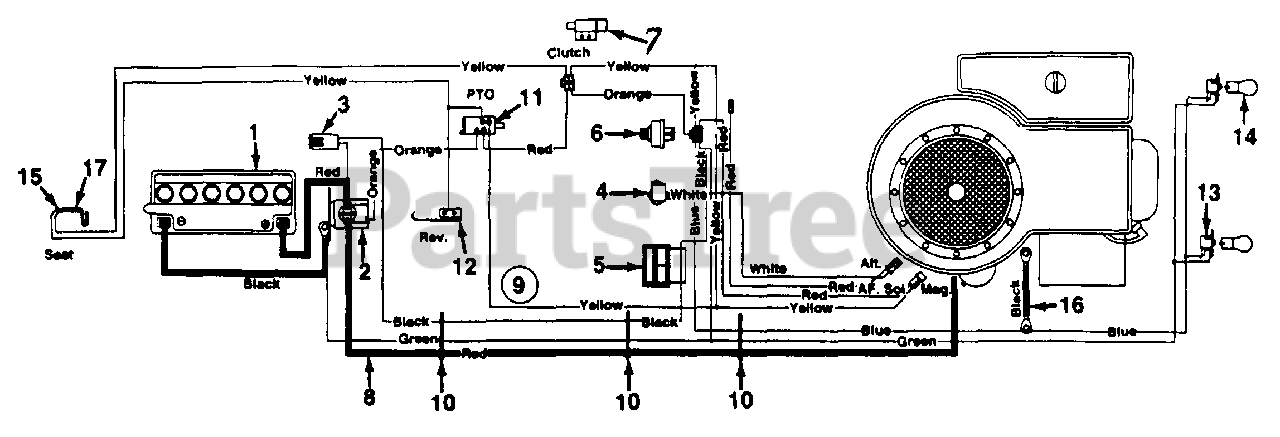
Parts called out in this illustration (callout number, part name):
1	Battery
2	Solenoid
3	Fuse 7.5 Amps
4	Light Switch
5	Ammeter
6	Ignition Switch
7	Safety Switch (Clutch)
8	Electric Wire 30" Lg.
9	Wire Harness w/Ammeter
10	Cable Tie
11	Safety Switch (Deck)
12	Safety Switch (Reverse)
13	Socket
14	Bulb (Headlight)
15	Safety Switch (Seat)
16	Ground Wire 7.5" Lg.
17	Safety Switch (Seat)
